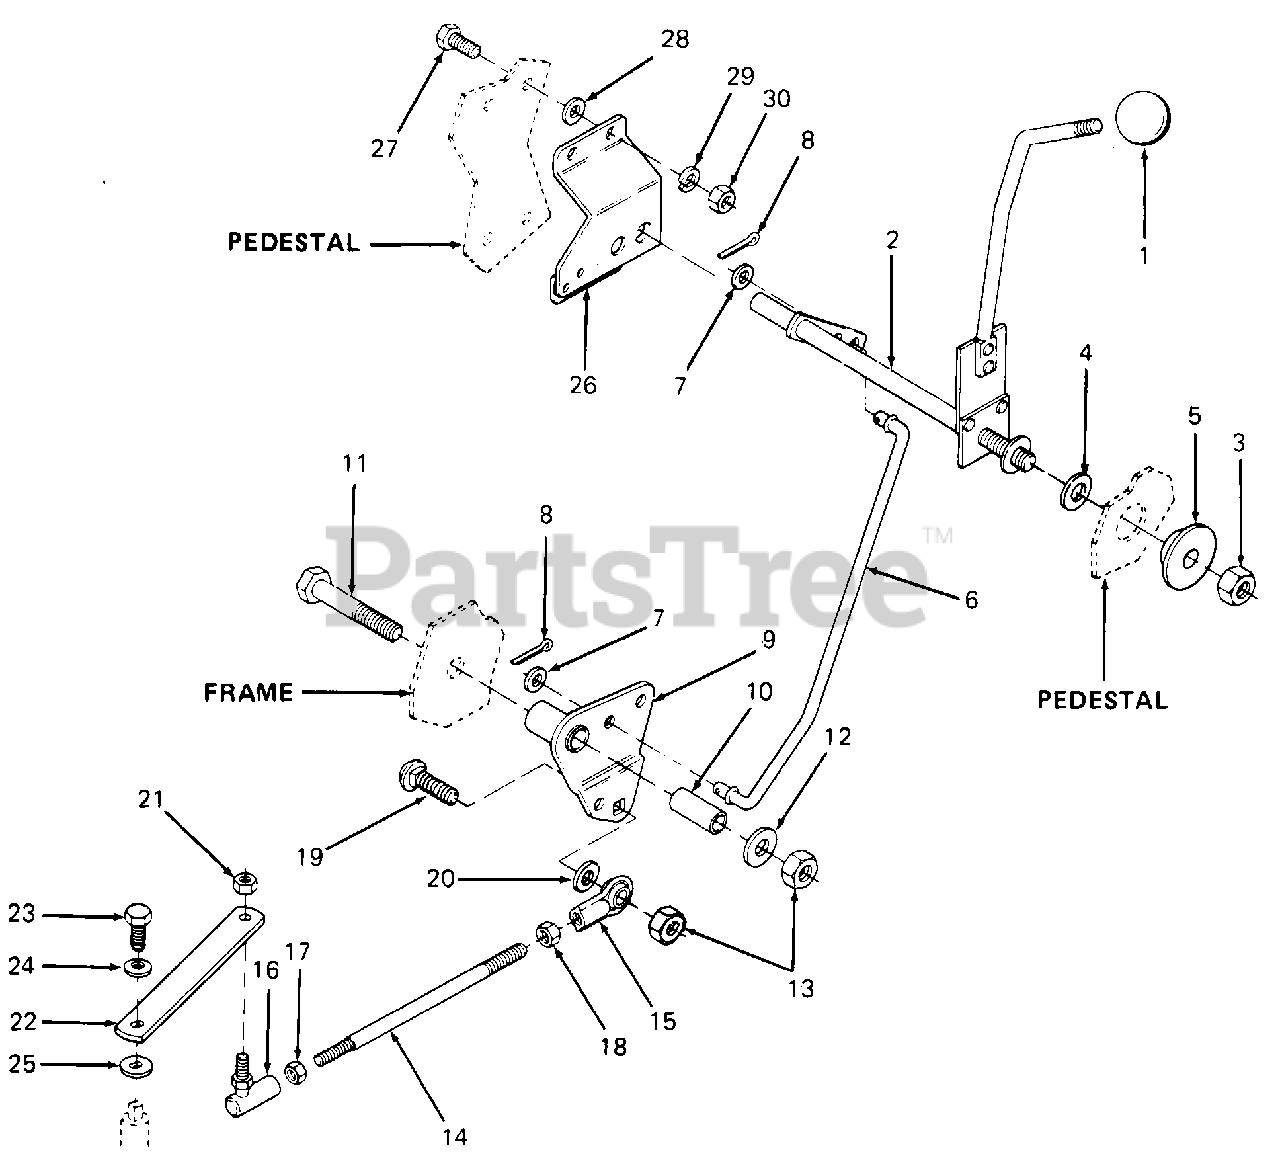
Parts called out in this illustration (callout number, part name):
1	Knob, Control
2	Shifter Assembly
3	Nut, Hex Top Lock, 1/2-20
4	Washer, Friction
5	Spacer, Shoulder
6	Rod, Upper Shift
7	Washer, Flat, .406 X .75 X.063 Thk
8	Pin, Cotter, 1/8 X 1.0 Lg
9	Cam, Shift
10	Sleeve, .380 X .623 X 1.555 Lg
11	Screw, Hex Cap, 3/8-16 X 2.25 Lg GR5
12	Washer, Flat, .385 X .87 X 0.6 Thk HDN
13	Nut, Hex Center Lock, 3/8-16
14	Rod, Shifter
15	Joint, Ball
16	Joint, Ball - LH Trd
17	Nut, Hex Jam, 5/16-24 LH Trd GR5
18	Nut, Hex Jam, 3/8-24 GR5
19	Bolt, Sht Nk Carr, 3/8-16 X 1.0 Lg GR5
20	Washer, Flat, .385 X .62 X .063
21	Nut, Hex Patch Lock, 5/16-24
22	Lever, Shifter
23	Screw, Hex Patch Lock, 1/4-28 X .62 Lg GR5
24	Washer, Bell
26	Bracket, Clutch Handle
27	Screw, Hex Cap, 1/4-20 X .62 Lg GR5
28	Washer, Flat, .281 X .75 X .105
29	Washer, Lock, 1/4
30	Nut, Hex, 1/4-20 GR5
